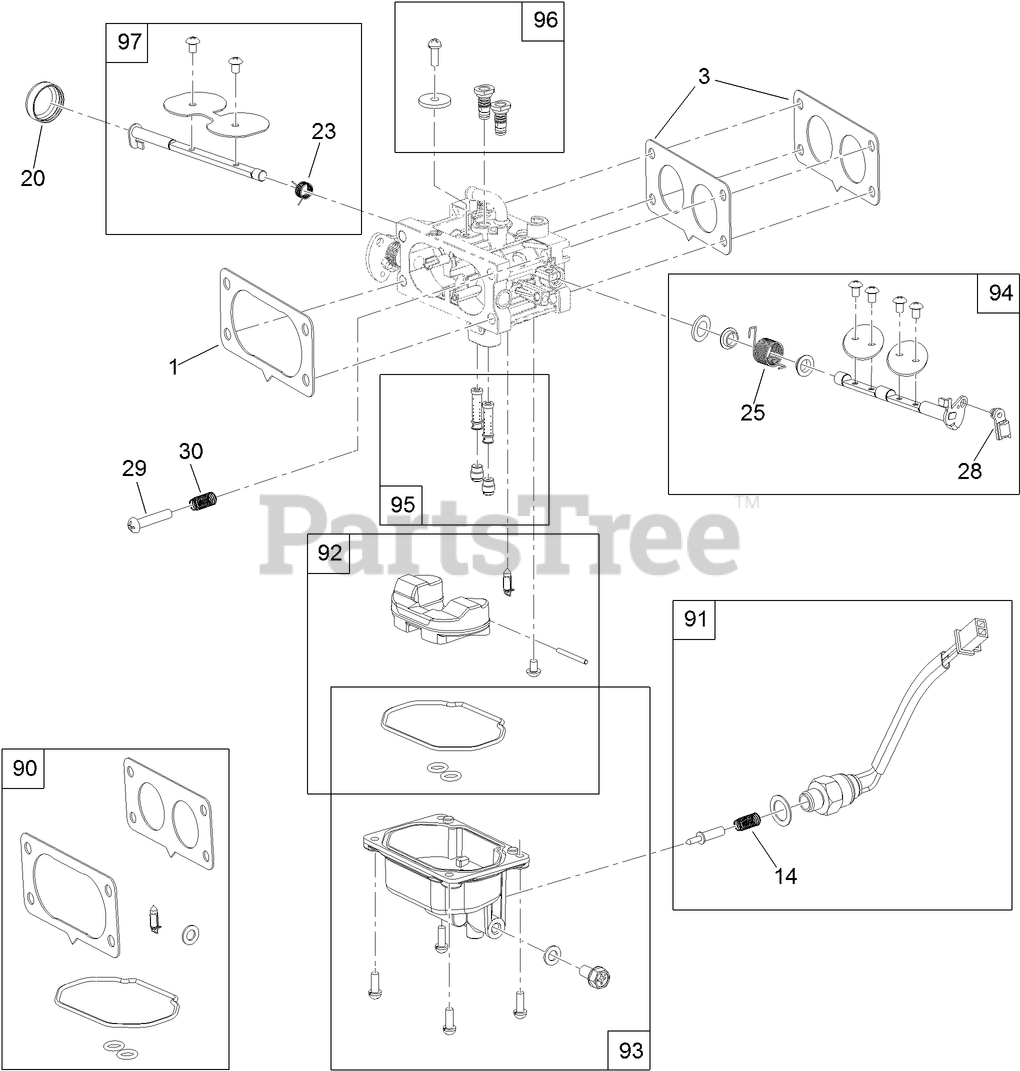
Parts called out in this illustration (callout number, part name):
1	GASKET-CARBURETOR
3	GASKET-CARBURETOR
14	SPRING
20	COVER-SHAFT, CHOKE
23	SPRING
25	SPRING
28	CLAMP-LOCK
29	SCREW-PPH
30	SPRING
90	CARBURETOR REPAIR KIT
91	SOLENOID KIT
92	FLOAT KIT
93	BOWL KIT
94	THROTTLE SHAFT KIT
95	NOZZLE AND JET KIT
96	IDLE JET KIT
97	CHOKE SHAFT KIT
